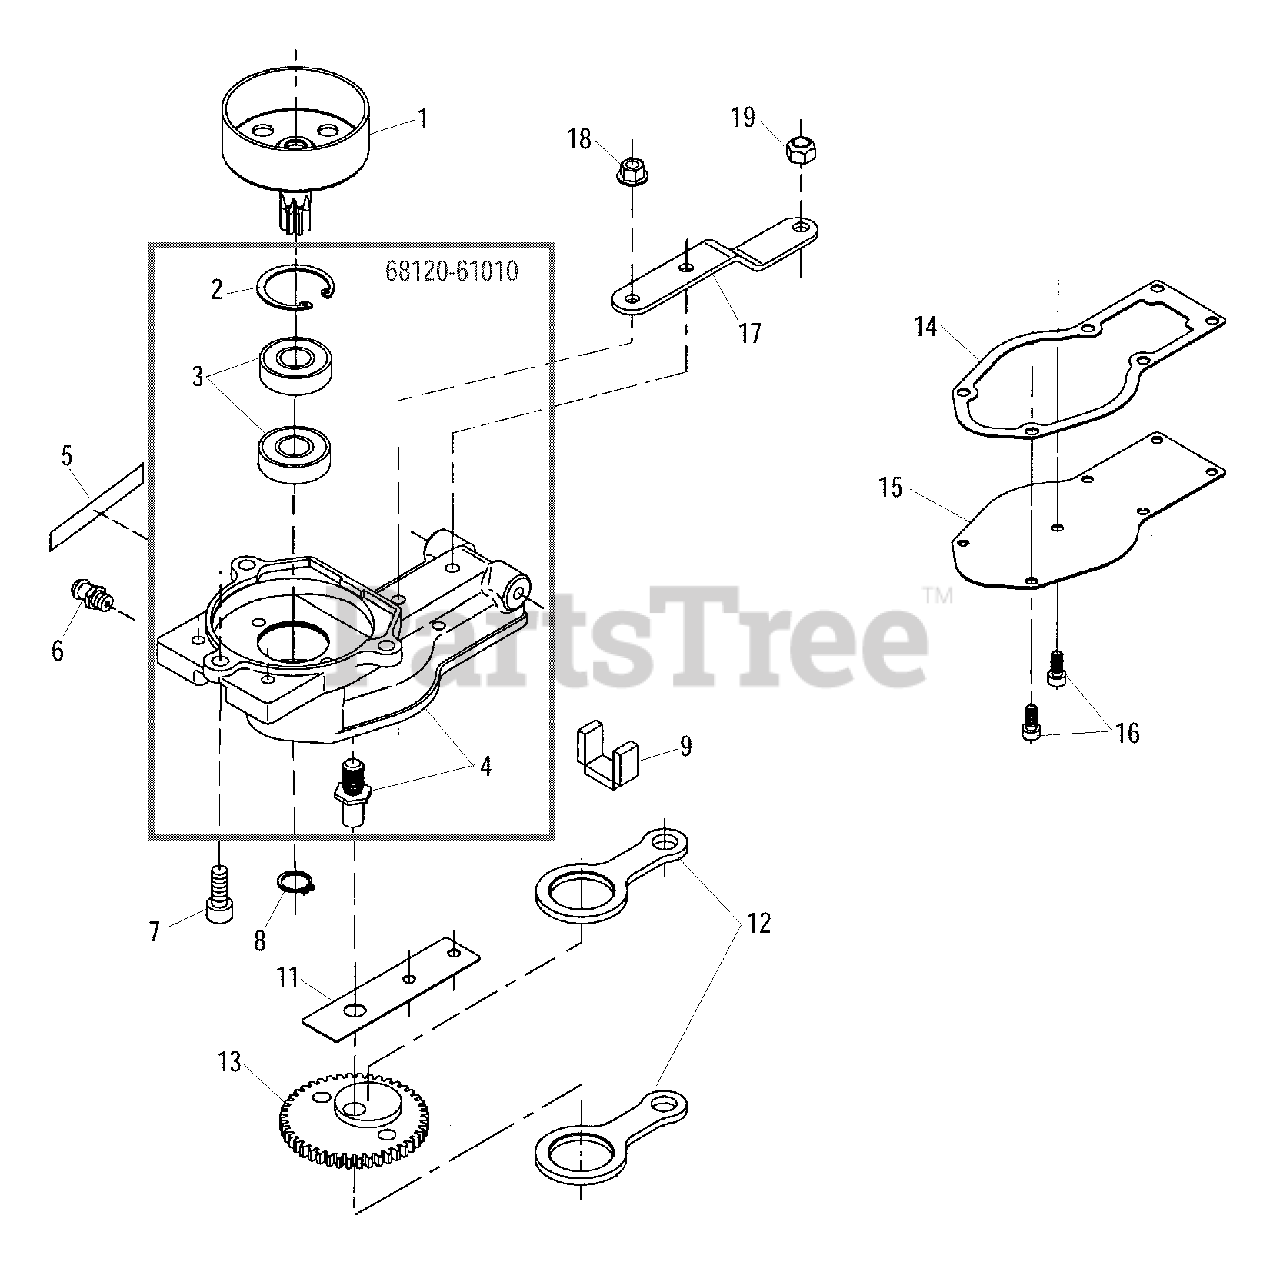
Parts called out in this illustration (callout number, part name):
1	DRUM, CLUTCH
2	RING, RETAINING - 28
3	BEARING, BALL - 6001DDU
4	CASE, GEAR
5	LABEL - LUBRICATION
6	FITTING, GREASE
7	SCREW - 6X16
8	RING, RETAINING - 12
9	SEAL, FELT
11	PLATE
12	ROD, CONNECTING
13	CAM GEAR
14	GASKET
15	PLATE, GEAR CASE
16	SCREW - 4X10
17	BRACKET, CUTTER
18	NUT - 5 -- FLANGE
19	LOCKNUT
68120-61010	GEAR CASE ASSY
